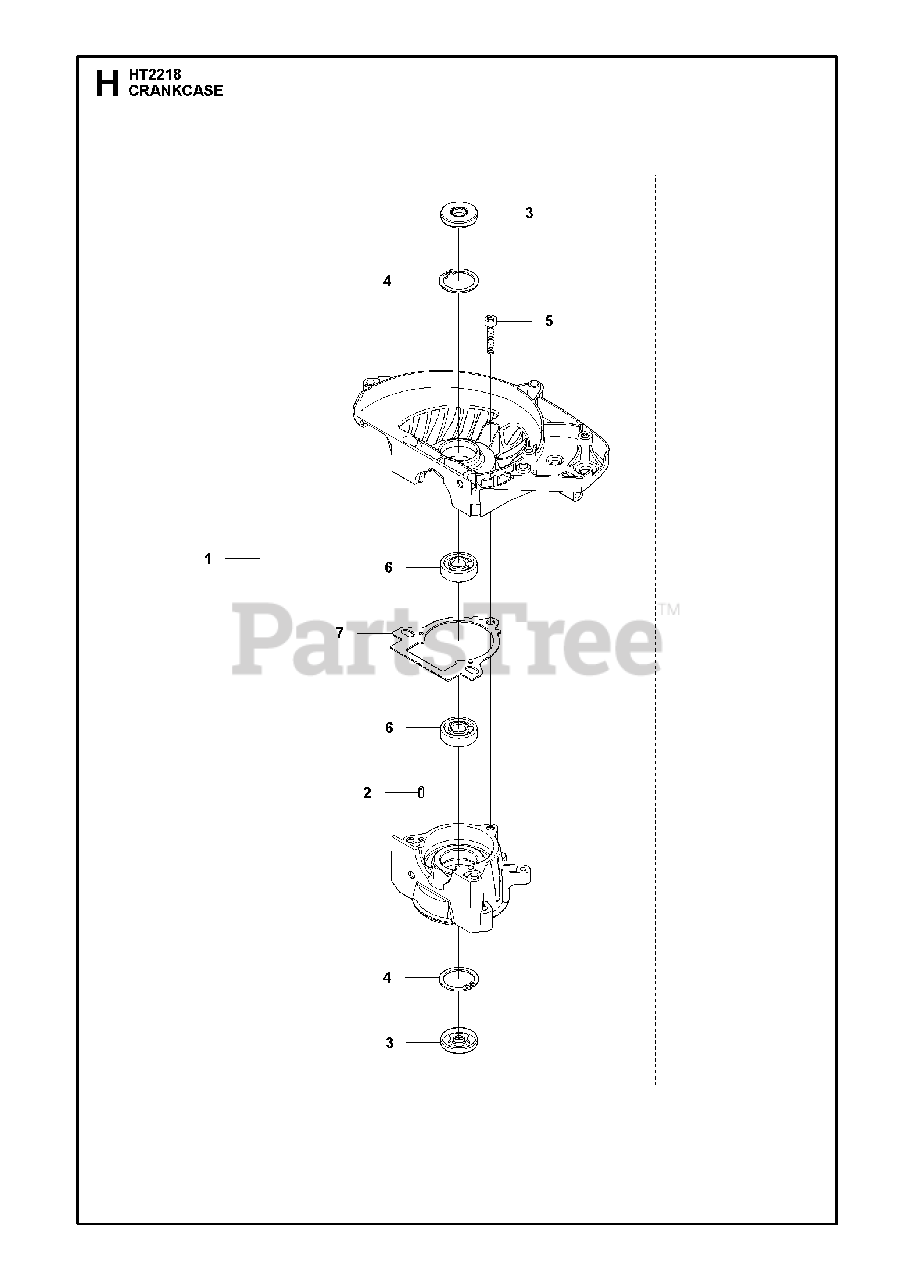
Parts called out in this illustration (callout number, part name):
1	CRANKCASE
2	PIN
3	SEALING RING
4	RETAINING RING SGH 26
5	SCREW
6	BALL BEARING
7	GASKET
